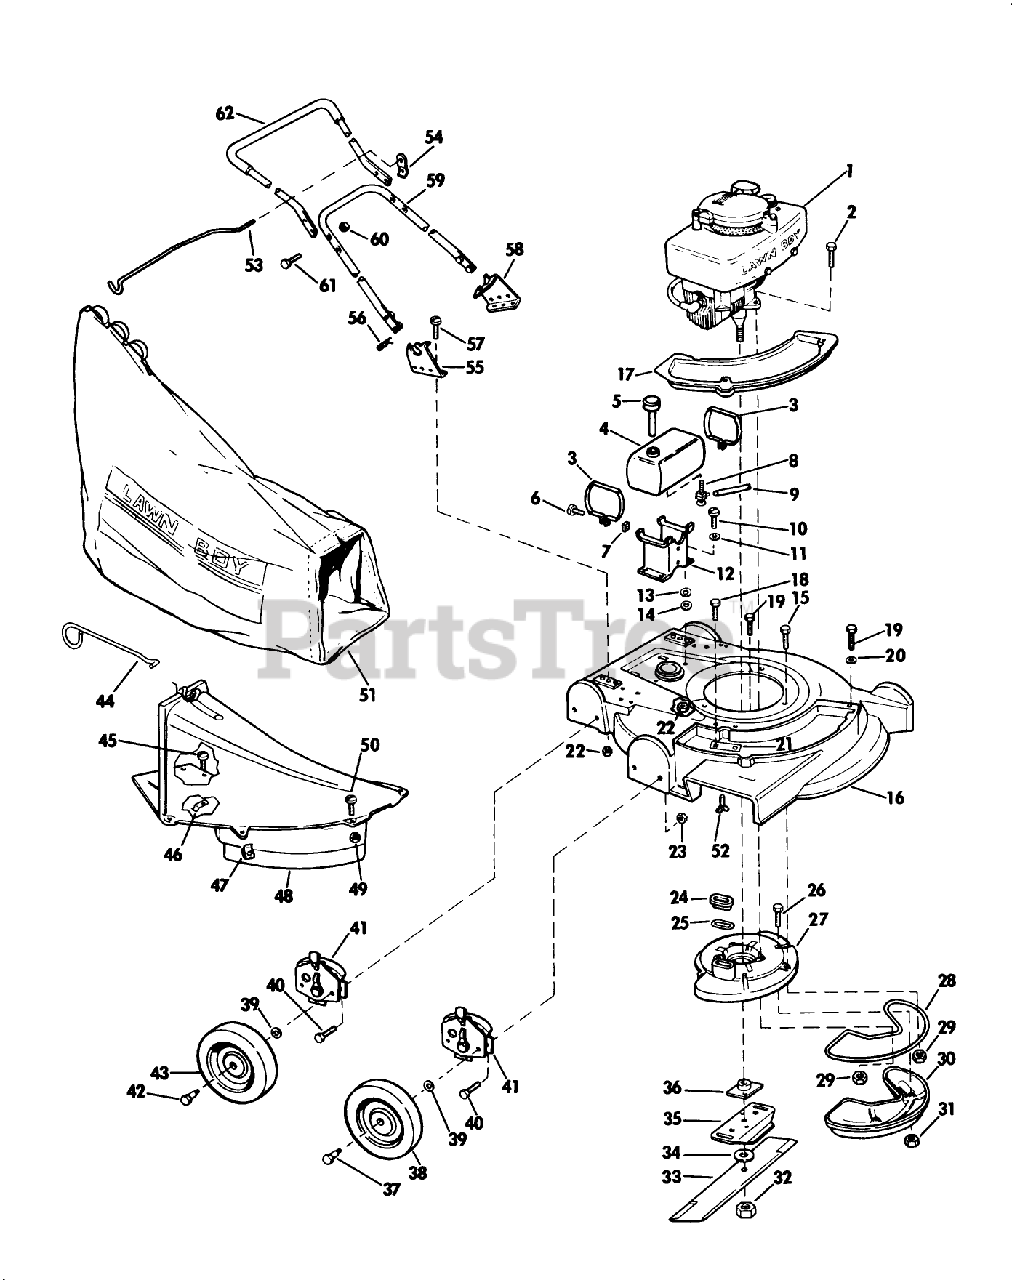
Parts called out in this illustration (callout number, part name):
8	VALVE&SCREEN SM
18	SCREW SEMS TRM HEX HD
19	SCREW SEMS TRM HEX HD
25	GASKET S
31	LOCKNUT E
32	NUT-BLADE
36	PLATE AND COLLAR ASM
37	BOLT WHEEL
39	WASHER WROUGHT
41	Height Adjustment Assy.
42	BOLT-SHOULDER
47	SPEED NUT ARDEN
48	Chute Skirt Assembly (Includes Hardware)
51	89802 LB WHOLE GOODS
53	ROD & CLIP
57	SCREW S
60	STOP NUT
62	Handle Grip Assy. Top
